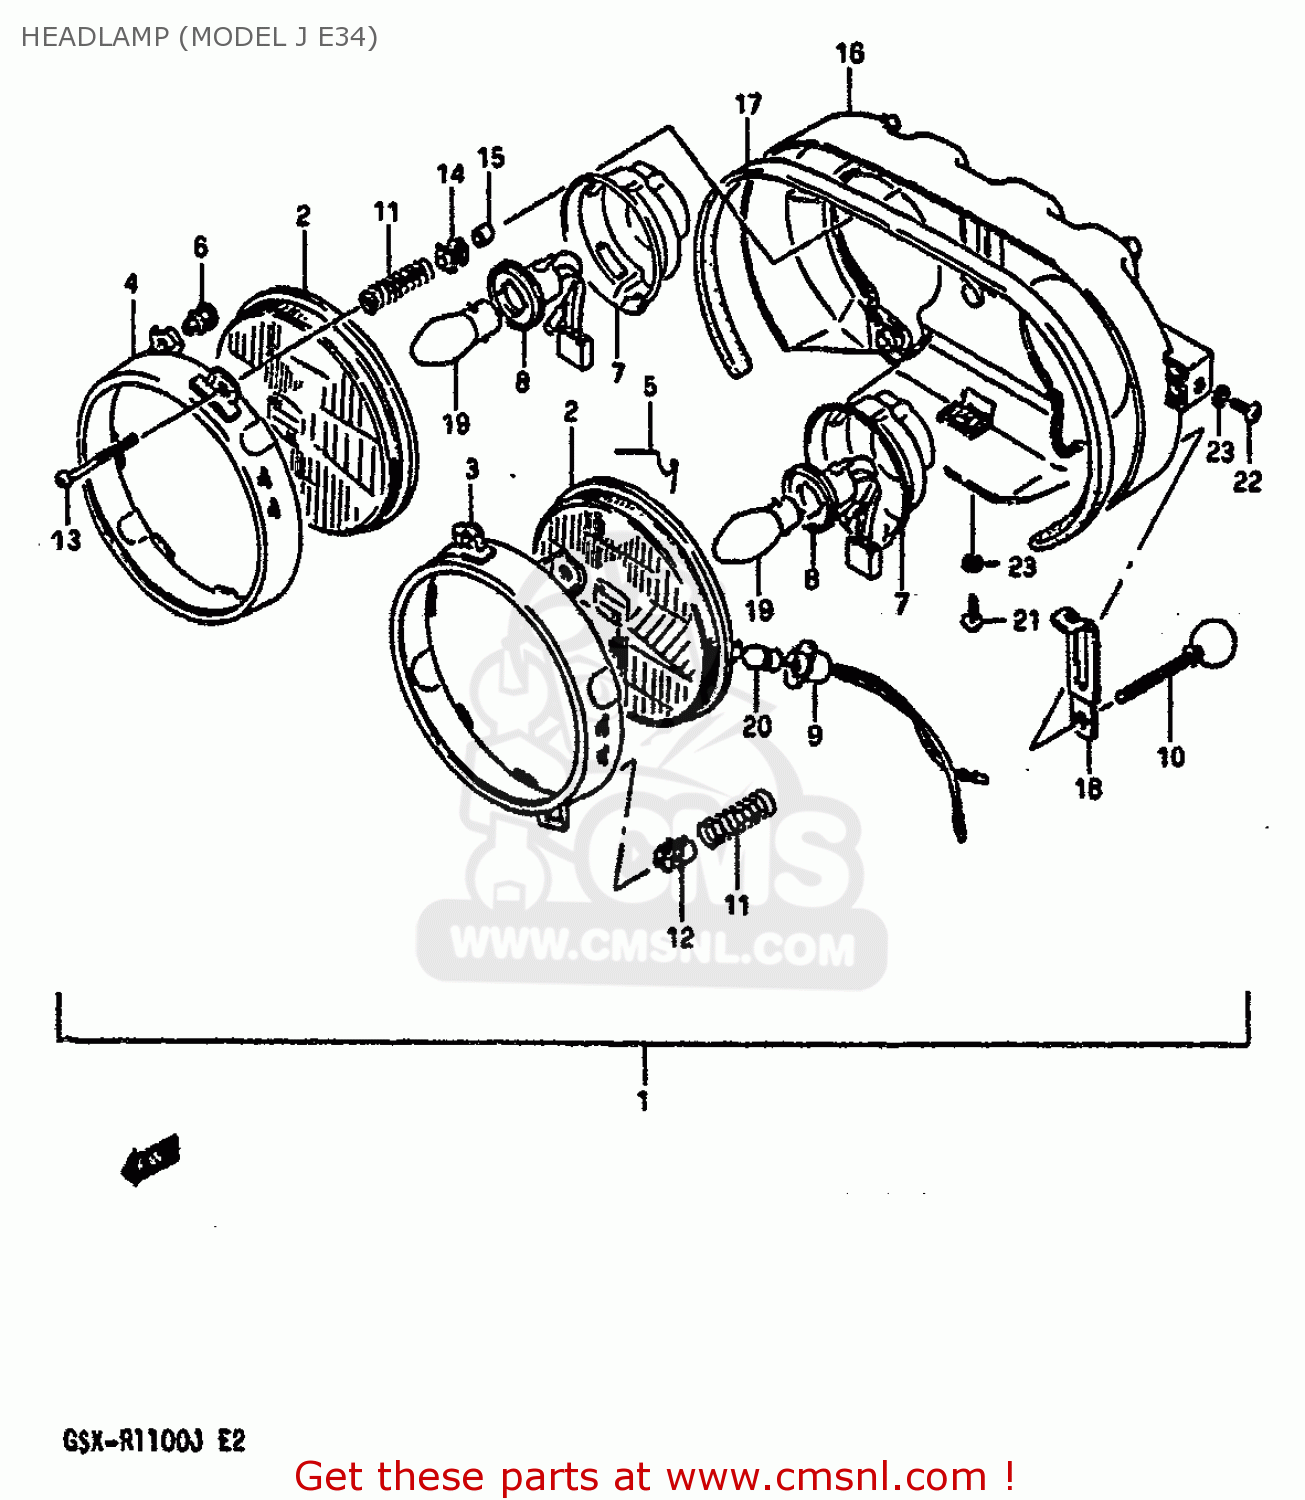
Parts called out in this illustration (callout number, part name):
1	HEADLAMP ASSY
2	UNIT
3	RING,RETAINING,LEFT
4	RING,RETAINING,RIGHT
5	SPRING
6	SCREW,SPHERICAL
7	COVER, SOCKET
8	SOCKET
9	SOCKET & CORD
10	SCREW,ADJUSTER
11	SPRING
12	NUT
13	SCREW,ADJUSTER
14	NUT
15	CAP,SCREW
16	HOUSING,HEADLAMP
17	GASKET (NAS)
18	CLAMP
19	BULB(12V35/35W)
20	BULB (12V,3W)
21	SCREW
22	SCREW
23	WASHER,LOCK
